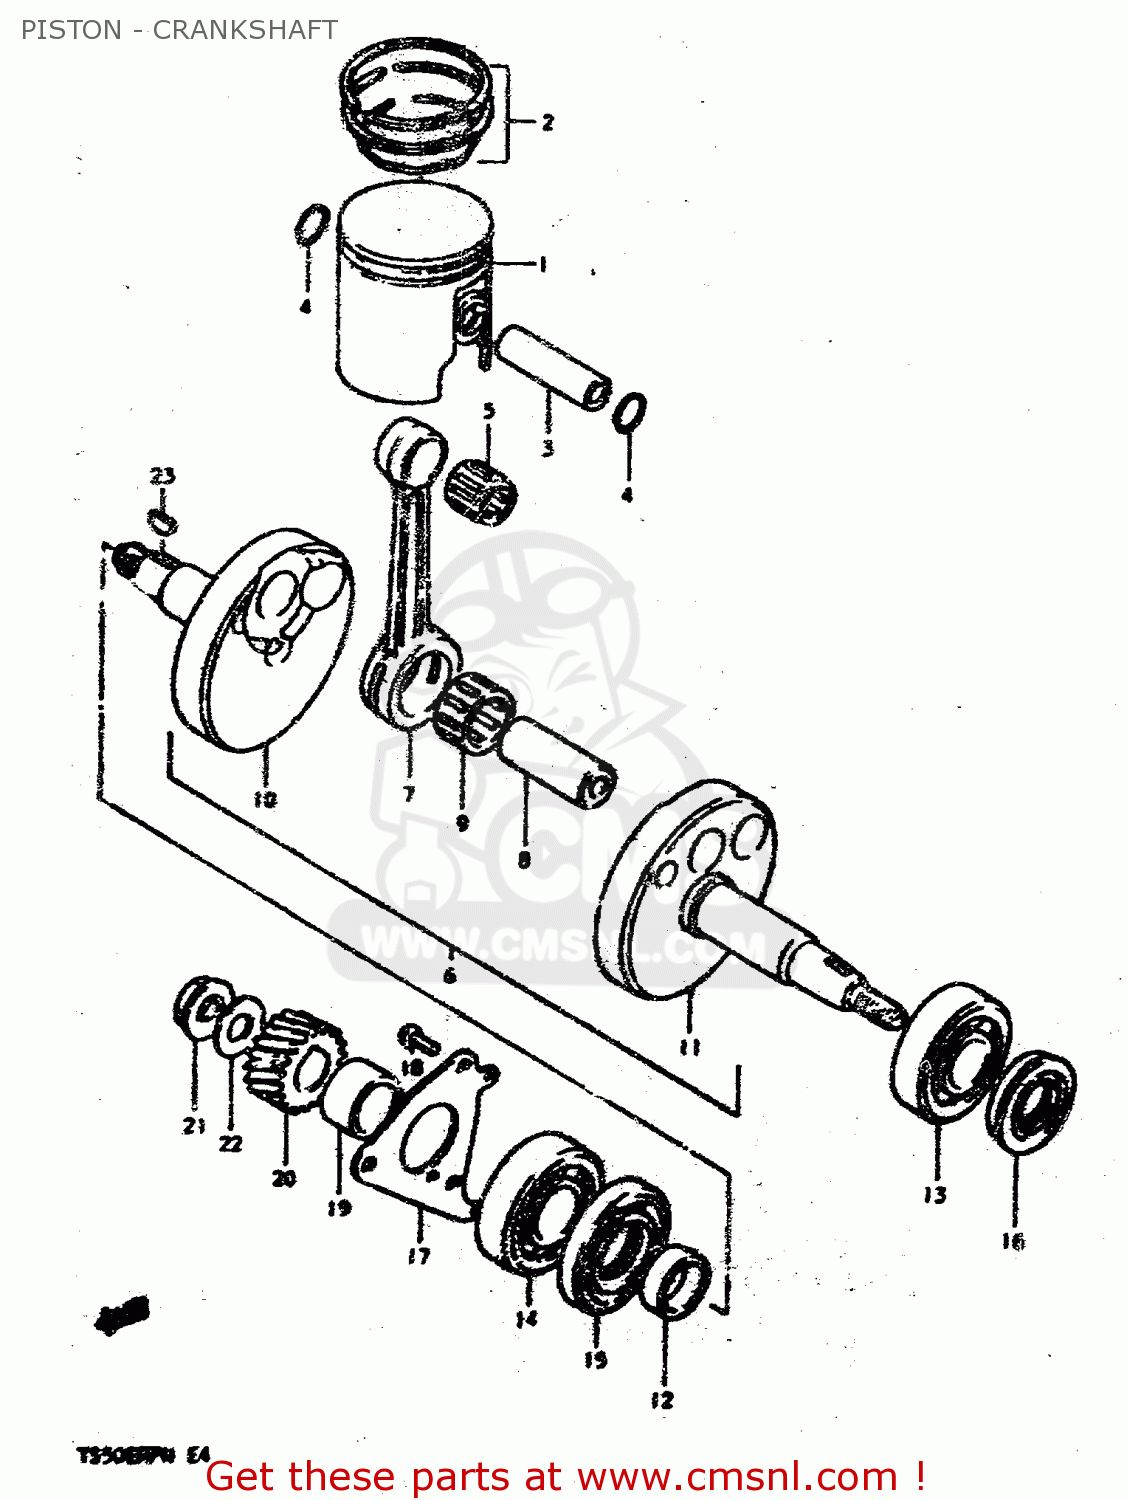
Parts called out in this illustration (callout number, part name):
1	PISTON
2	RING SET,PISTON
3	PIN,PISTON
4	RING,SNAP
5	BEARING
6	CRANKSHAFT ASSEMBLY
7	CONNECTING ROD
8	PIN, CRANK
9	BEARING
10	CRANKSHAFT,RIGHT
11	CRANKSHAFT,LEFT
12	SPACER(20X26X9)
13	BEARING
14	BEARING
15	OIL SEAL
16	OIL SEAL
17	RETAINER,CRANKSHAFT BEARING,R
18	SCREW 6X12
19	SPACER(20X26X14)
20	GEAR,PRIMARY DRIVE NO.19
21	NUT
22	WASHER
23	KEY
